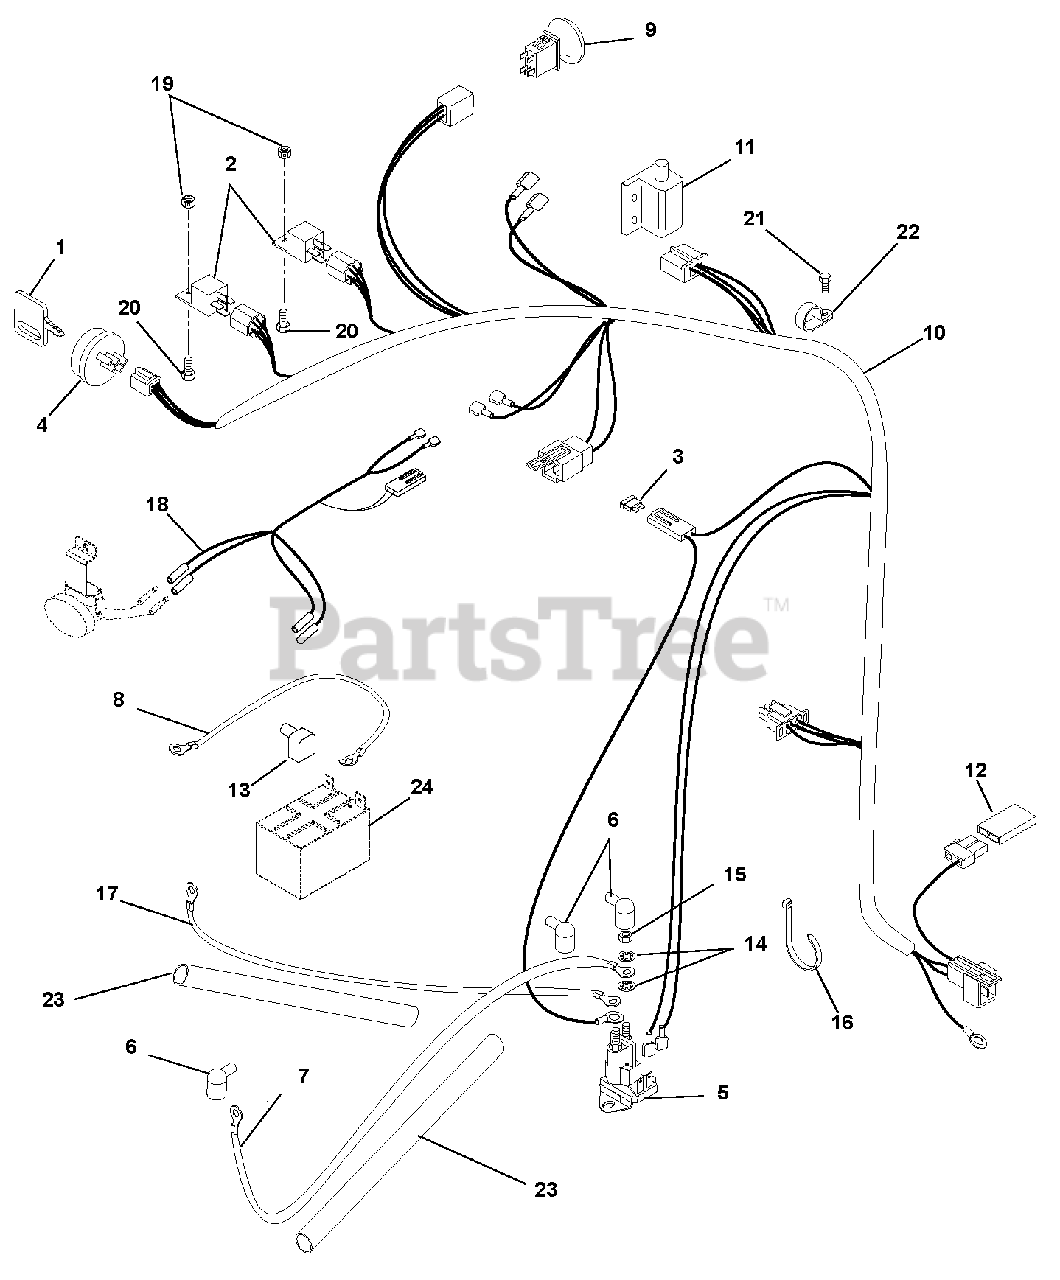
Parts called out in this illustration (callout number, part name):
1	Key with Cap
2	Relay
3	Fuse, 30 AMP
4	Key Switch
5	Solenoid
6	Boot, Eyelet Terminal
7	Starter Cable
8	Cable, Ground .25 x 13.00 x .31
9	Switch, Clutch With Retainer
10	Harness, ZTXL/ZoomXL
11	Switch, Double Pole N.O. / N.O.
12	Diode, Connector Shell
13	Insulator
14	Washer, Locking .31
15	Nut, Jam .31-24
16	Cable Tie
17	Positive Cable
18	Harness, Headlight
19	Nut, Locking Nylon With Insert 10-24
20	Screw, Hex Washer Head Machine 10-24 x .75
21	Screw, Tapping Hex Washer Head Thread Rolling .38-16 x .50
22	Clamp, Cushioned Steel .75
23	Sleeve, Anti-Abrasion
24	Battery, 12V, 215 CCA GEP
